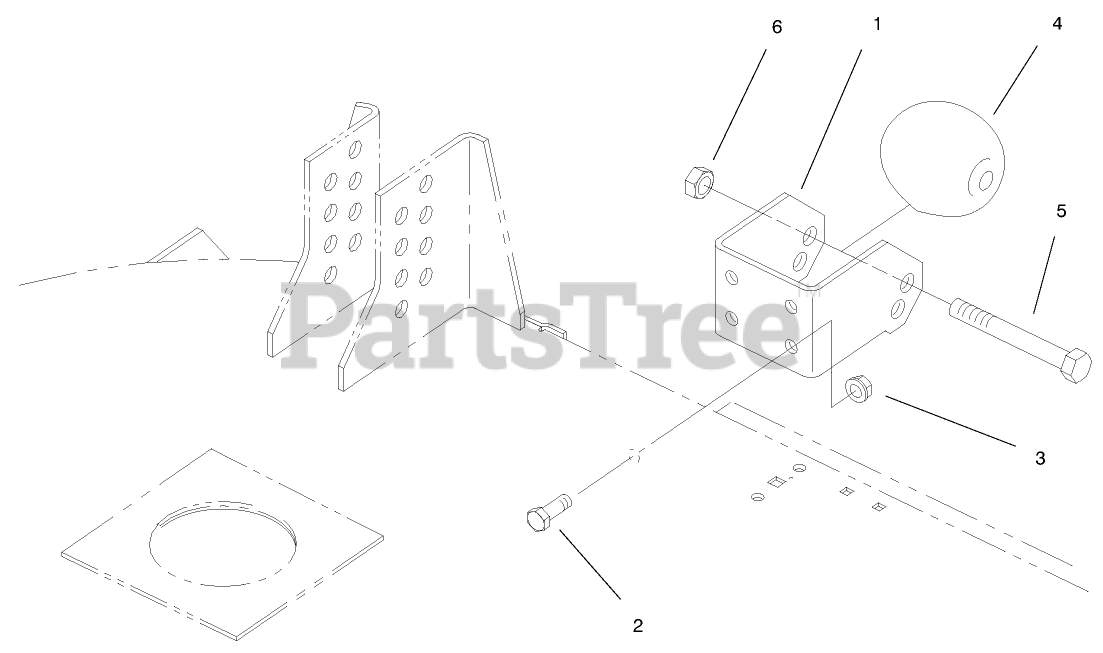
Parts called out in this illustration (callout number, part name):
1	BRACKET - ROLLER
2	SCREW-HH
3	NUT-LOCK, NI
4	ROLLER
5	SCREW-HH
6	NUT-LOCK, NI
